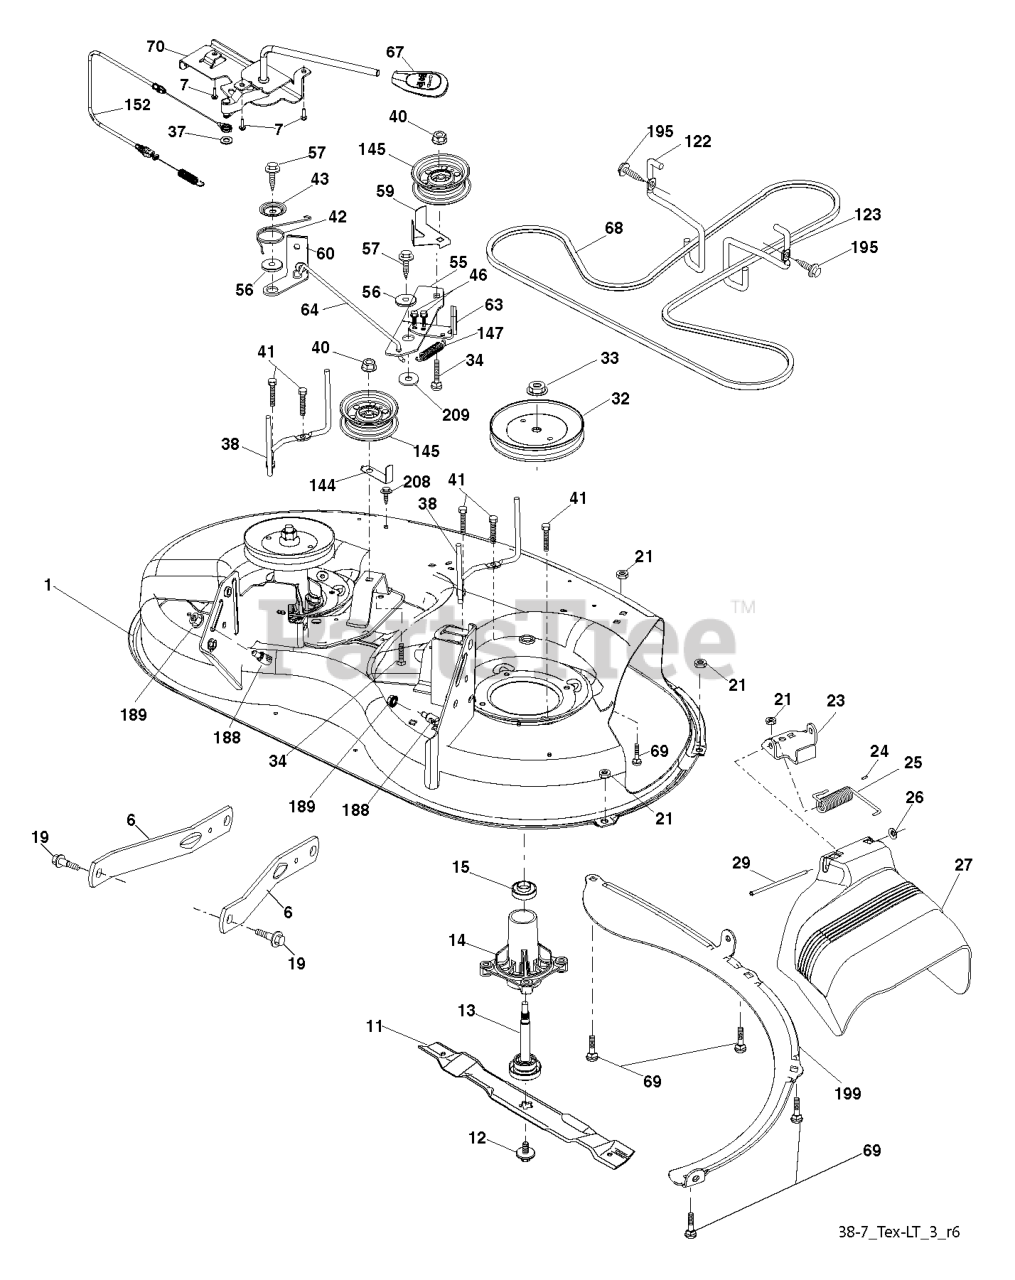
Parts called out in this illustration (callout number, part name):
1	DECK SVCX 38"194251X431
6	ARM.SUSPENSION.MOWER.R
7	SCREW.#10 X 0.750.BOS
11	BLADE.2 IN 1.38"DECK
12	SCREW.SEMS.7/16-20X1.HEX.HEAD
13	SHAFT ASM.MNDRL.N/GREASEABLE
14	RP.HOUSING.MANDREL.4PT.
15	BEARING.MANDREL.TOP.EXTENDED
19	BOLT.SHOULDER
21	LOCKNUT
23	BRKT.DEFLECTOR.38"2005+
24	CAP-SLEEVE LT
25	SPRING.TORSION.DEFLECT
26	NUT PUSH M
27	SHIELD.DEFLECTOR.MWR.38-7/97CM
29	ROD.HINGE
32	PULLEY.MANDREL.5.0.PD.38"
33	NUT.FLANGE.LOCK.TOP
34	BOLT.3/8-16X1.50
37	WASHER
38	KEEPER BELT LH MANDREL
40	NUT LOCK FLG 3/8-16 UNC
41	BOLT.HEX.WASHR.HED.313-18X1.19
42	SPRING.TORSION.BRAKE
43	SRPING.TORSION.RETAINE
46	SCREW.1/4-20X5/8
56	SPACER.RETAINER
57	SCREW 3/8-16X1
59	GUARD, BELT
60	ARM BRAKE MOWER RH 38"
63	RP ARM.BRAKE.MOWER.38"LH.TEX
64	LINK BRAKE
67	HANDLE.CLUTCH.CABLE.LT
69	BOLT
70	CLUTCH.ASM.MANUAL.LT.PRED
122	KEEPER BELT ENGINE LH
123	KEEPER BELT RH
144	KEEPER BELT
145	PULLEY.IDLER.48"PRIMARY
147	SPRING RETURN
152	CABLE.CLUTCH.MANUAL.
188	STUD.FASTNER.W/ANTI-ROTATE
189	NUT LOCK HEX FLANGE 5/16-18
195	SCREW, 3/8-16X3/4
199	BAFFLE.VORTEX.FRONT.38"
208	SCREW 3/8-16X1/2
209	WASHER 12/32X2X10GA
